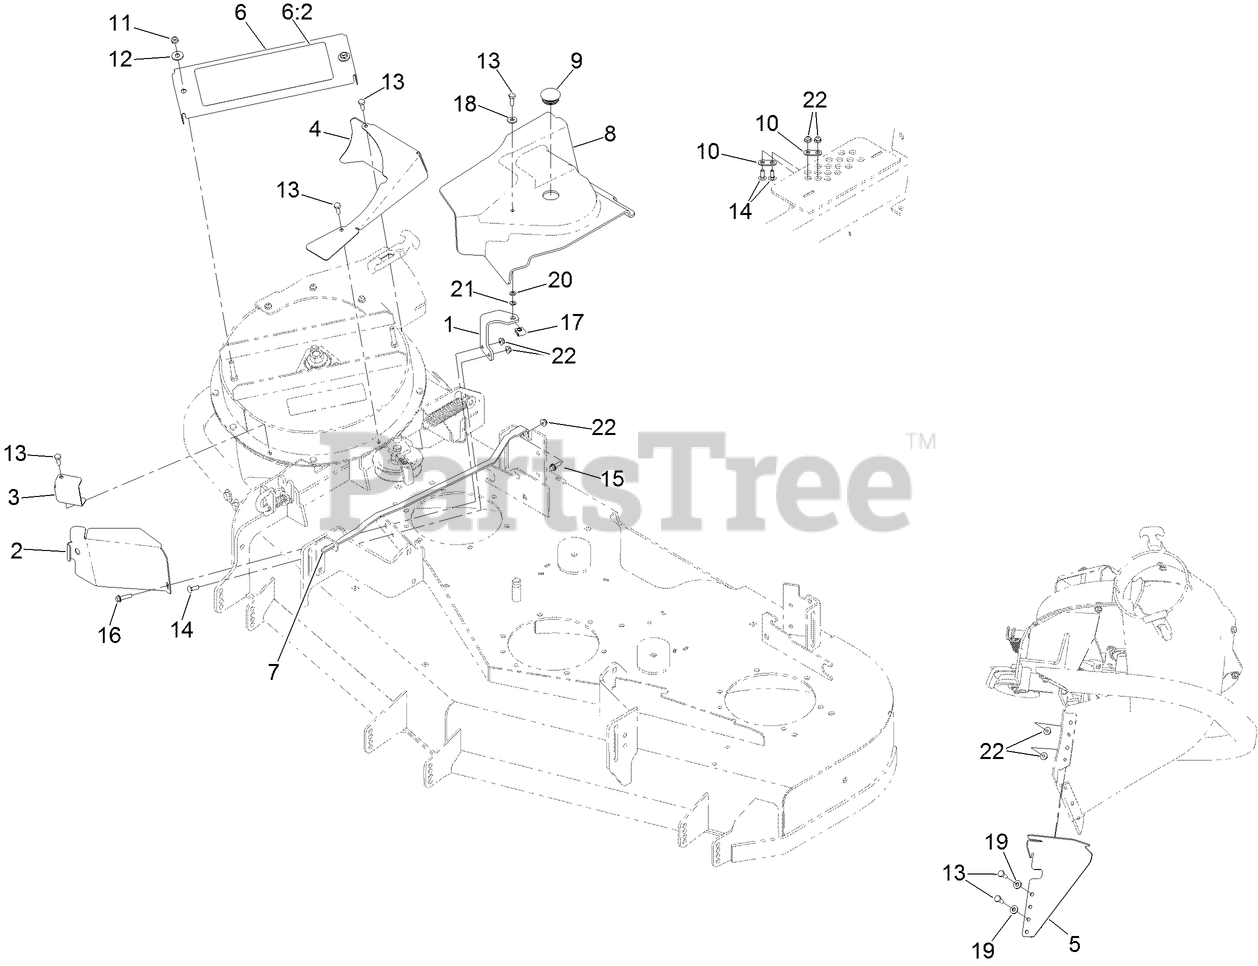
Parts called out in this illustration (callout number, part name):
1	BRACKET-COVER, BELT
2	GUARD-BAGGER
3	GUARD-FRONT, LEFT
4	GUARD-TOP
5	GUARD-BAGGER
6	COVER-BEARING
6:2	DECAL-DANGER
7	BRACKET-SKIRT, LOWER
8	BELT-COVER
9	PLUG-PLASTIC
10	PLATE-COVER, HOC [BLACK]
11	NUT-LOCK, NI
12	WASHER-FLAT
13	SCREW-HH
14	BOLT-CARR
15	SCREW-HHF
16	SCREW-HHF
17	NUT-SPEED
18	WASHER-FLAT
19	WASHER-FLAT
20	WASHER-FLAT
21	PUSHNUT-RETAINER, BOLT
22	NUT-HF
